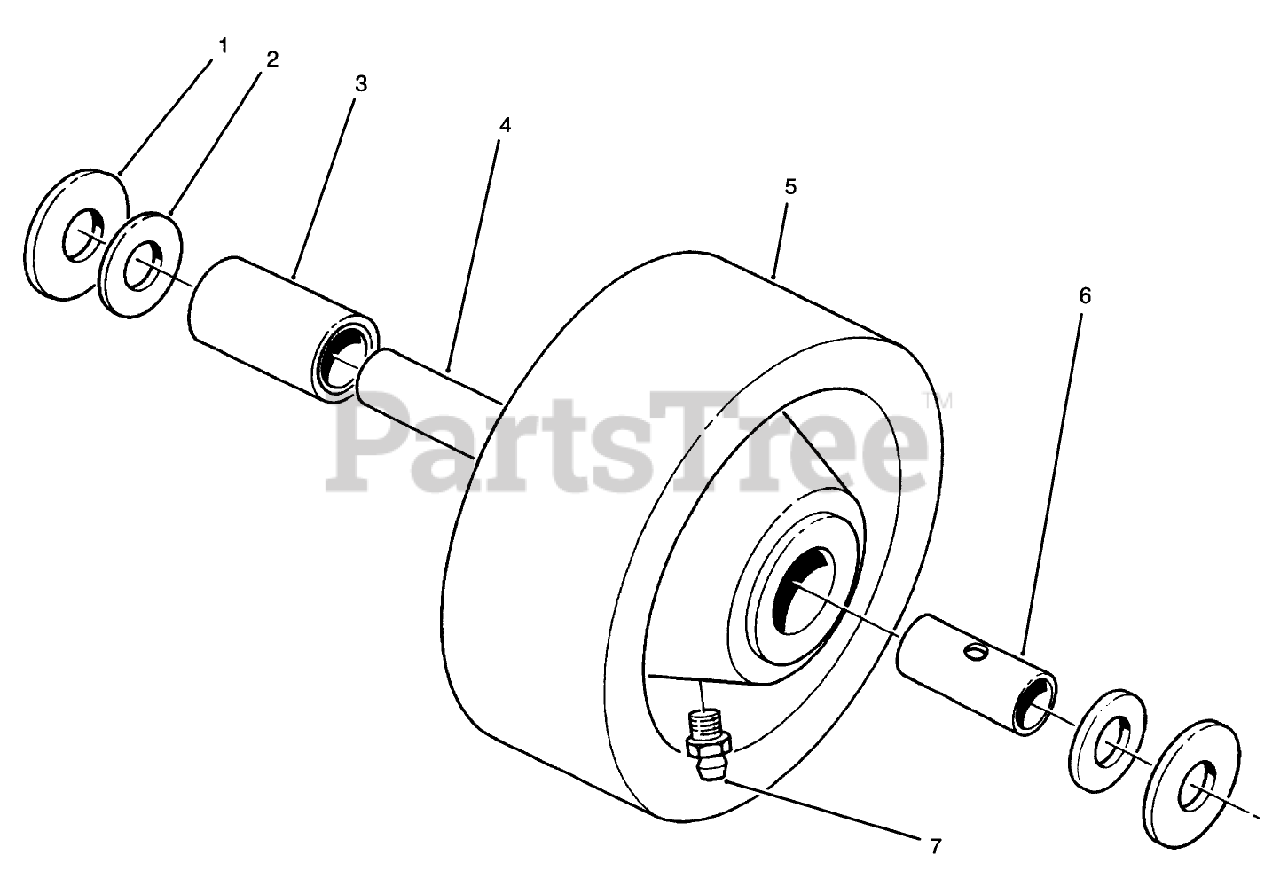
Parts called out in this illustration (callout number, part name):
1	THRUST WASHER
2	BEARING RETAINER
3	ROLLER BEARING
4	SPANNER-TIRE
5	WHEEL
6	SPANNER BUSHING
7	FITTING-GREASE
